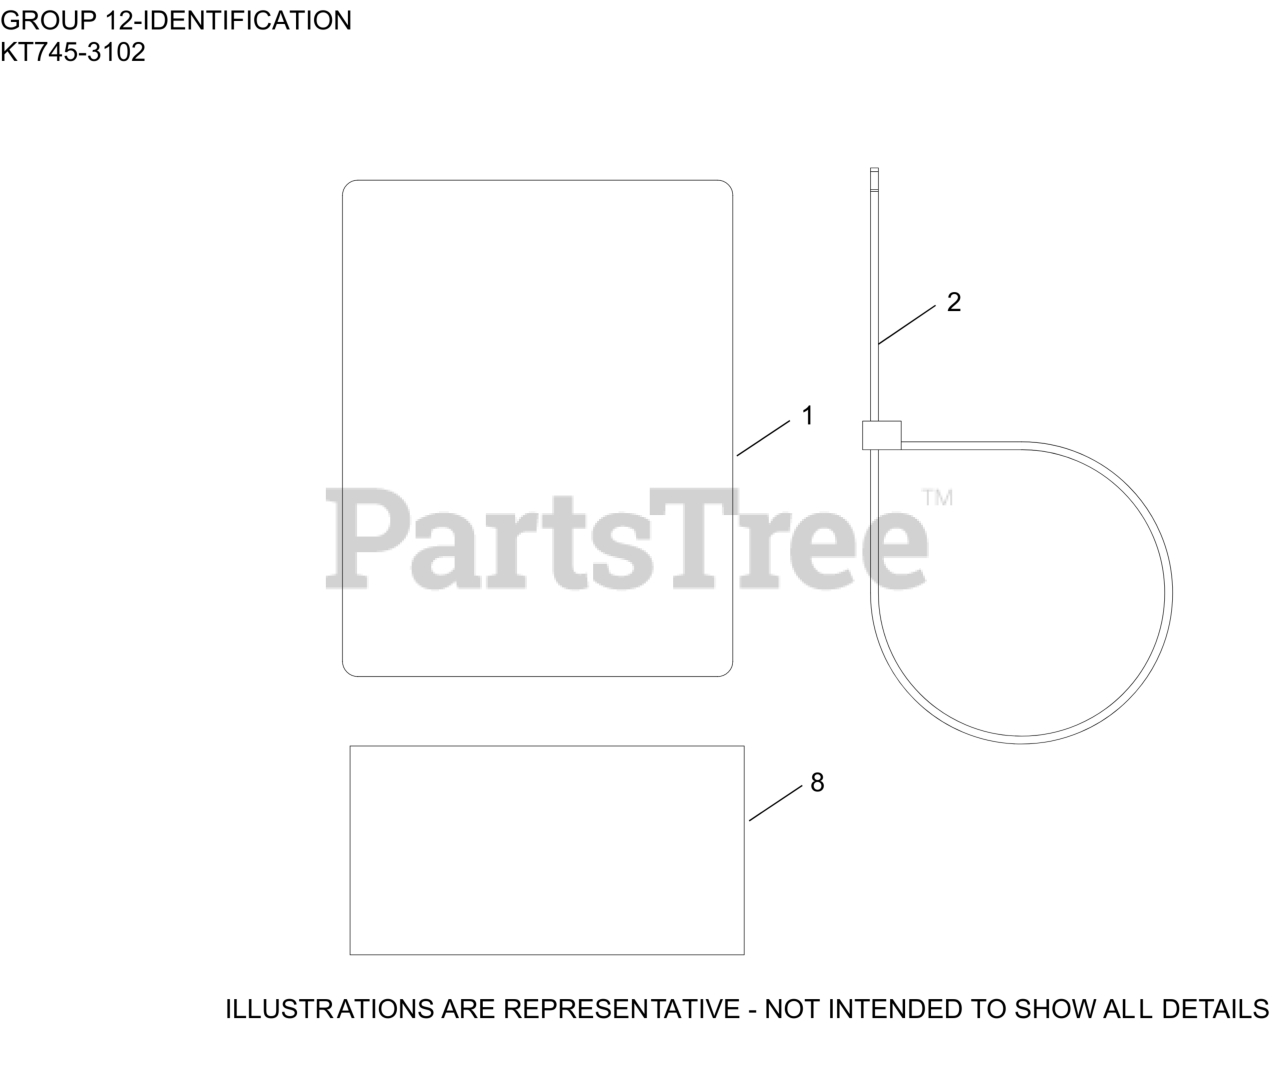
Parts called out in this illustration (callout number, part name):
1	LABEL, CLEAR LAMINATION
8	DECAL, USA
NI	LABEL, 7000 SERIES KT745 (26 HP)
